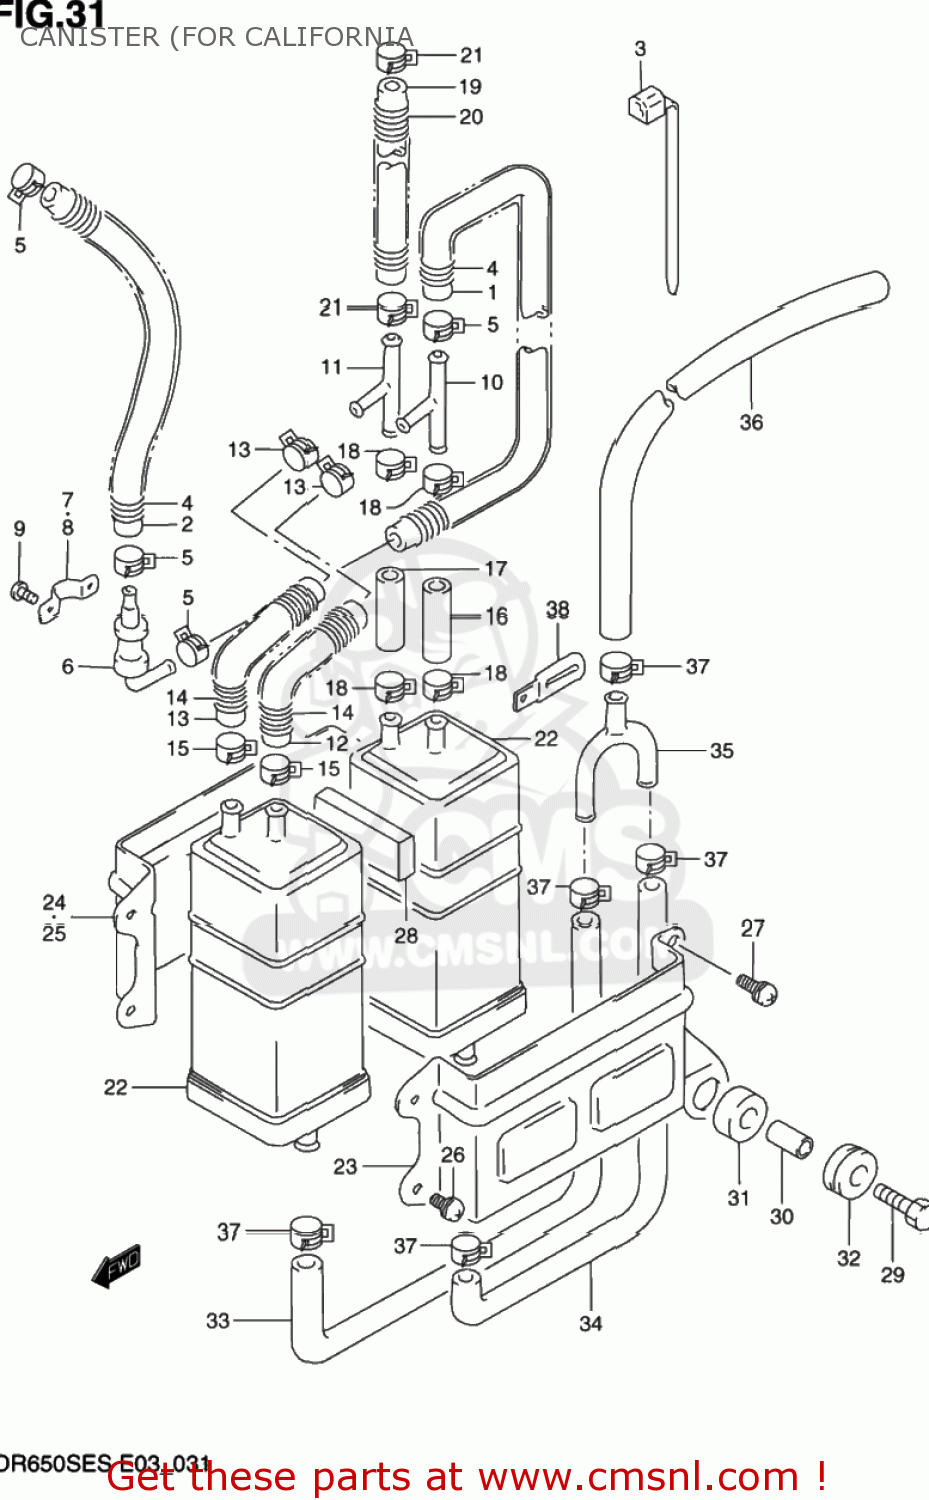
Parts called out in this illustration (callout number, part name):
1	HOSE (5.4X11.4X600)
2	CLAMP L:165
3	SPRING
4	CLIP
5	VALVE,FUEL TANK BREATHER
6	PLATE COMP,ROLL OVER VALVE
7	CUSHION
8	PLATE,FUEL TANK BREATHER NO.2
9	CUSHION
10	SCREW
11	BOLT
12	SPACER (6.2X20X14)
13	HOSE (5.4X11.4X600)
14	(CA) SPRING
15	(CA) SPRING
16	CANISTER ASSEMBLY,CHARCOAL
17	PLATE,CANISTER FITTING
18	HOSE(L:350)
19	CLIP
20	BOLT
21	BOLT
22	SPACER (6.8X10X8)
23	CUSHION
24	HOSE
25	(CA) SPRING
26	(CA) SPRING
27	CLAMP(L:125)
